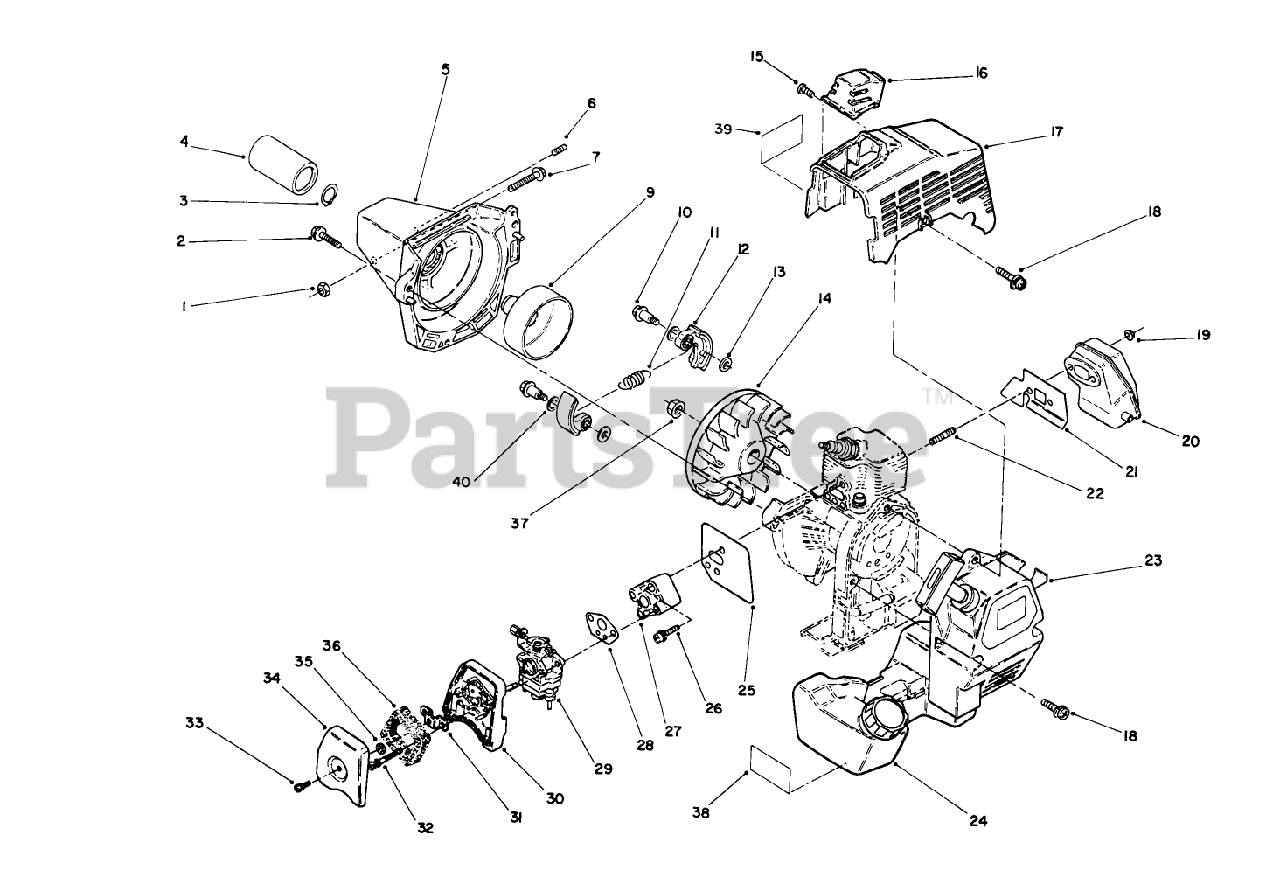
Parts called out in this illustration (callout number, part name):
2	BOLT AND WASHER
3	SNAPRING
4	Spacer
5	Housing-Clutch
6	SETSCREW
7	Screw/Washer
9	CLUTCH DRUM
10	CLUTCH BOLT
11	Spring
12	SHOE, CLUTCH
13	WASHER
14	Fan
15	SCREW & WASHER
16	SPARK PLUG GUARD
17	TOP SHIELD
18	SCREW & WASHER
19	MUFFLER FLANGE NUT
20	MUFFLER
21	MUFFLER GASKET
22	MUFFLER STUD
23	RECOIL ASSEMBLY
24	Fuel Tank Assembly
25	INSULATOR GASKET
26	SCREW & WASHER
27	INSULATOR
28	CARBURETOR GASKET
29	Carburator Assembly
30	CLEANER CASE
31	BRACKET
32	SCREW W/ WASHER
33	SCREW & WASHERE
34	CLEANER COVER
36	CLEANER ELEMENT
38	DECAL - FUEL TANK
39	DECAL-SURFACE, HOT
40	SPRING WASHER
